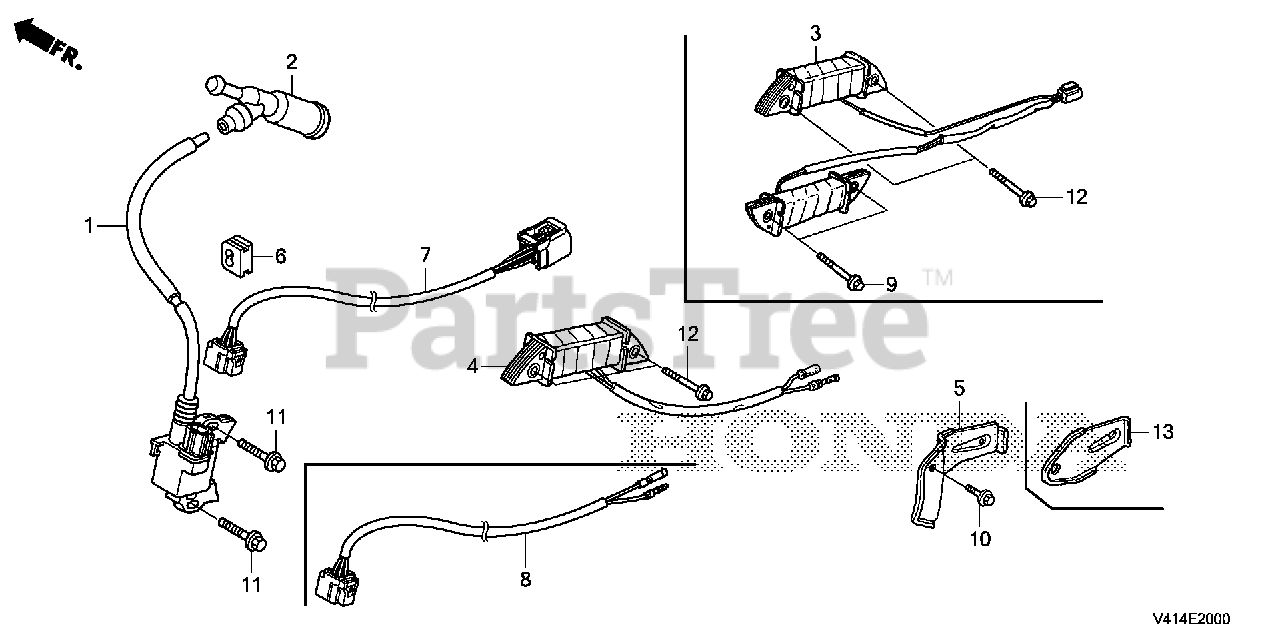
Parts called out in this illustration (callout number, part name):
1	COIL ASSY., IGNITION
2	CAP ASSY., NOISE SUPPRESSOR (NGK Y-EZD)
4	COIL ASSY., LAMP (12V/15W)
6	GROMMET, WIRE
8	WIRE HARNESS ASSY., ENGINE
10	BOLT, FLANGE (6X12) (CT200)
11	BOLT, FLANGE (6X28) (CT200) Use up to Engine SN 1530314.
12	BOLT, FLANGE (6X23)
13	CLAMP, WIRE
